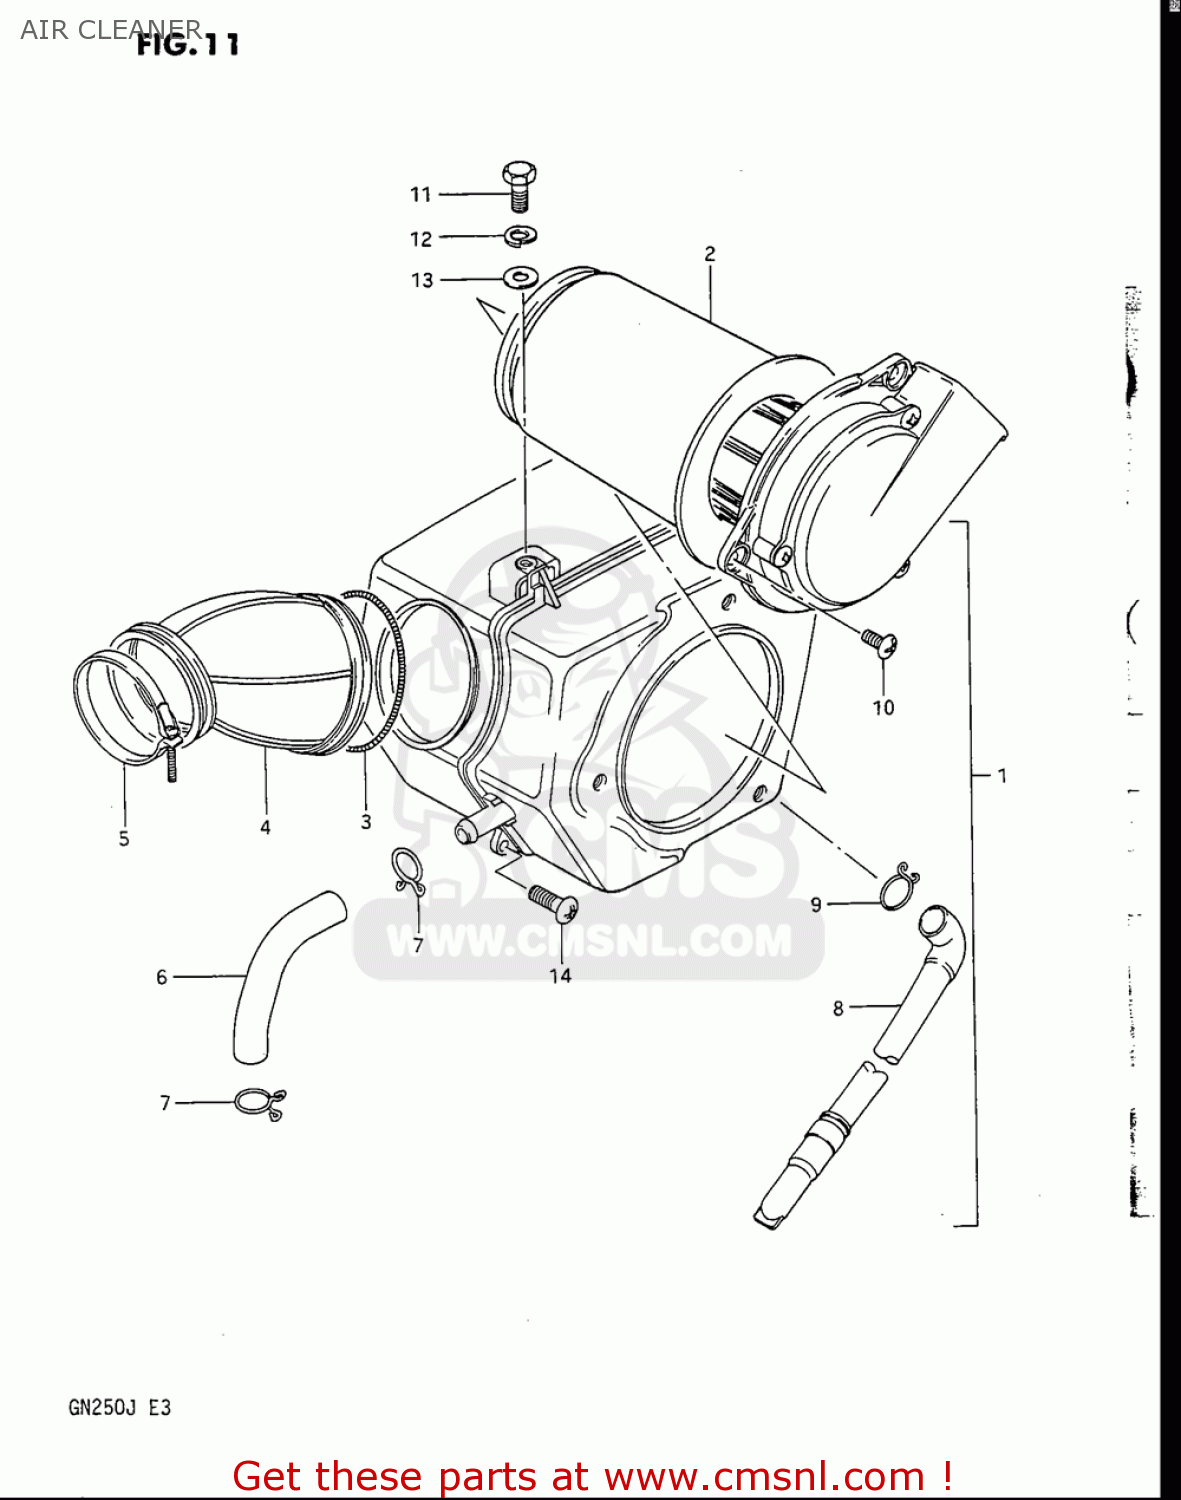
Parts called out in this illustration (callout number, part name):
1	CLEANER ASSY,AIR
2	FILTER
3	CLAMP,AIR CLEANER SIDE
4	TUBE,OUTLET
5	CLAMP
6	TUBE,BREATHER
7	CLIP
8	TUBE,DRAIN
9	CLIP
10	SCREW
11	BOLT
12	WASHER,LOCK
13	WASHER(6.5X18X1.6)
14	SCREW
